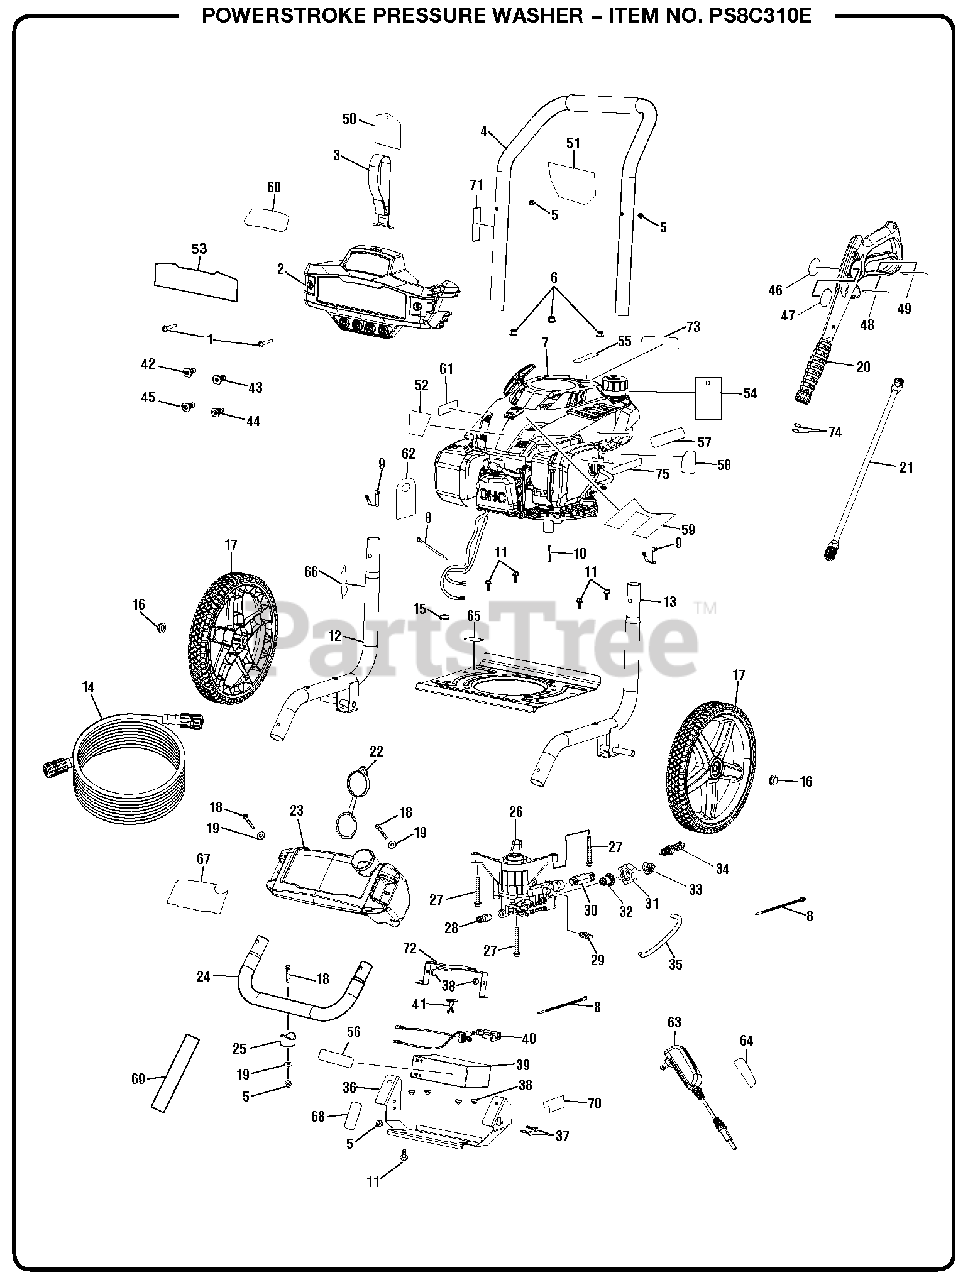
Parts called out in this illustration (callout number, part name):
1	Bolt (M6 x 42 mm, T30 Torx Pan Hd.)
2	Hose And Nozzle Assembly
3	Hose Strap
4	Handle Assembly w/ Foam
5	Lock Nut (M6 x 1)
6	Flange Lock Nut (M8 x 1.25)
7	Engine (Subaru 190V, E-Start)
9	Handle Spring Clip
10	Output Shaft Key (35 mm)
11	Bolt (M6 x 1 x 16 mm, Hex Hd.)
12	Main Frame Assembly (Left)
13	Main Frame Assembly (Right)
15	Rubber Grommet
16	Push Cap Nut
18	Screw (M6 x 1 x 48 mm, T30 Torx Pan Hd.)
19	Washer (1/4 in.)
20	Trigger Handle Assembly
21	Wand Assembly
22	Soap Tank Cap
23	Soap Tank
24	Front Frame Assembly
26	Pump
27	Flange Bolt (M8 x 1.25 x 60 mm, Hex Hd.)
28	Thermal Release Valve
29	Soap Injector Kit
30	Outlet Tube
33	Filter Screen (Pump Inlet)
34	Unloader Valve Assembly
35	Chemical Siphon Tube
36	Battery Mount Bracket
37	Screw (M4 x 12 mm, T20 Torx Pan Hd.)
38	Vibration Isolators
39	Battery
40	Battery & Charger Wire Harness
41	Cable Tie
42	25deg Nozzle
43	40deg Nozzle
44	0deg Nozzle
45	Soap Nozzle
46	Label (Trigger Handle Logo)
47	Label (Trigger Handle Warning)
48	Label (Trigger Handle Rating Label)
49	Label (Trigger Handle Warning, French & Spanish)
50	Standard Nozzle Hangtag
51	Quick Start Label
52	Electric Start Label
53	Performance Label
54	Warning Hangtag
55	E85 Label
56	Battery Replacement Label
57	Choke Label
58	Fuel Valve & Choke Label
59	On/Off Label
60	Electric Start Label
61	Hot Surface Label
62	Oil Dipstick Hangtag
63	Battery Charger
64	Battery Charger Label
65	Oil Fill Location Label
66	Combustion Warning Label
67	Detergent Tank Label
68	Battery Terminal Connector Flag
69	Charging Hangtag
70	Battery Bracket Label
71	Inquiries Label
72	Battery Hold Down Bracket
73	Danger Label (English)
75	EMC Label
